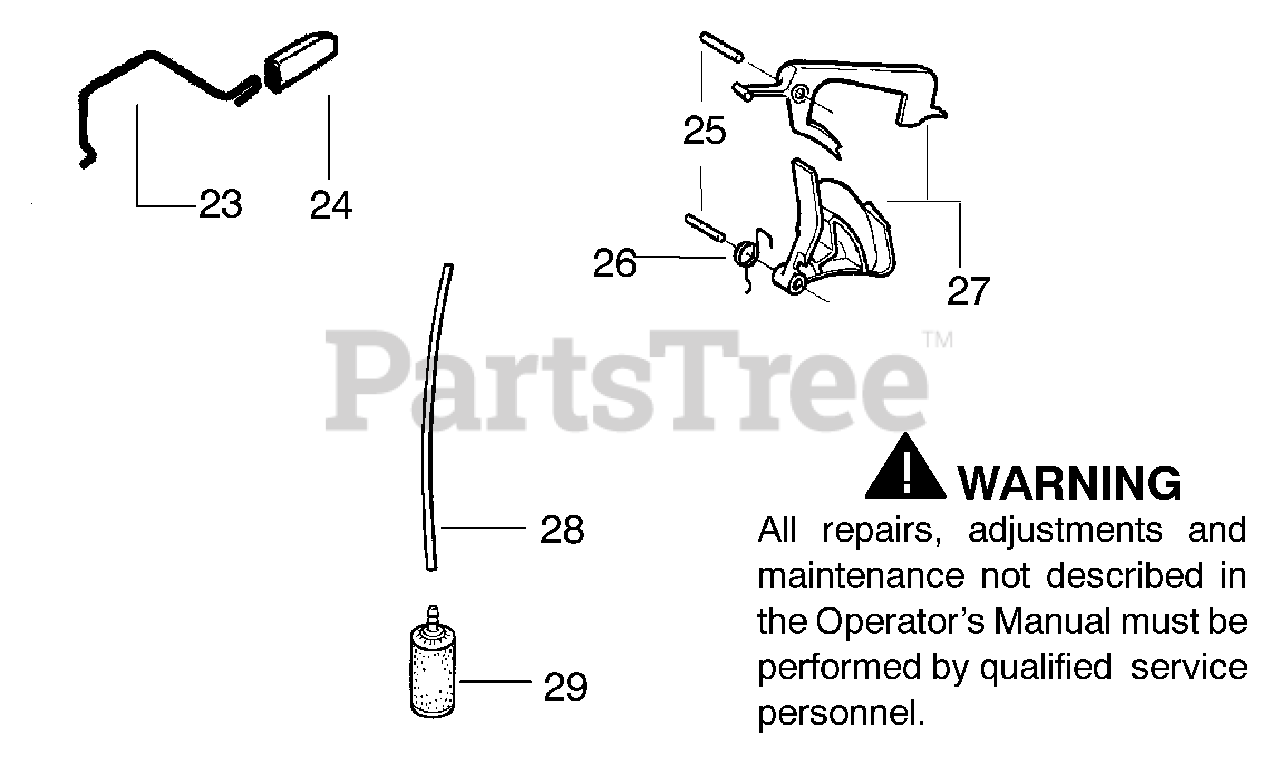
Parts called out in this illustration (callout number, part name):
23	Wire - Throttle
24	Cap - Wire
27	Kit - Throttle Trigger
28	Kit - Fuel line
29	Assy.- Fuel Pickup
